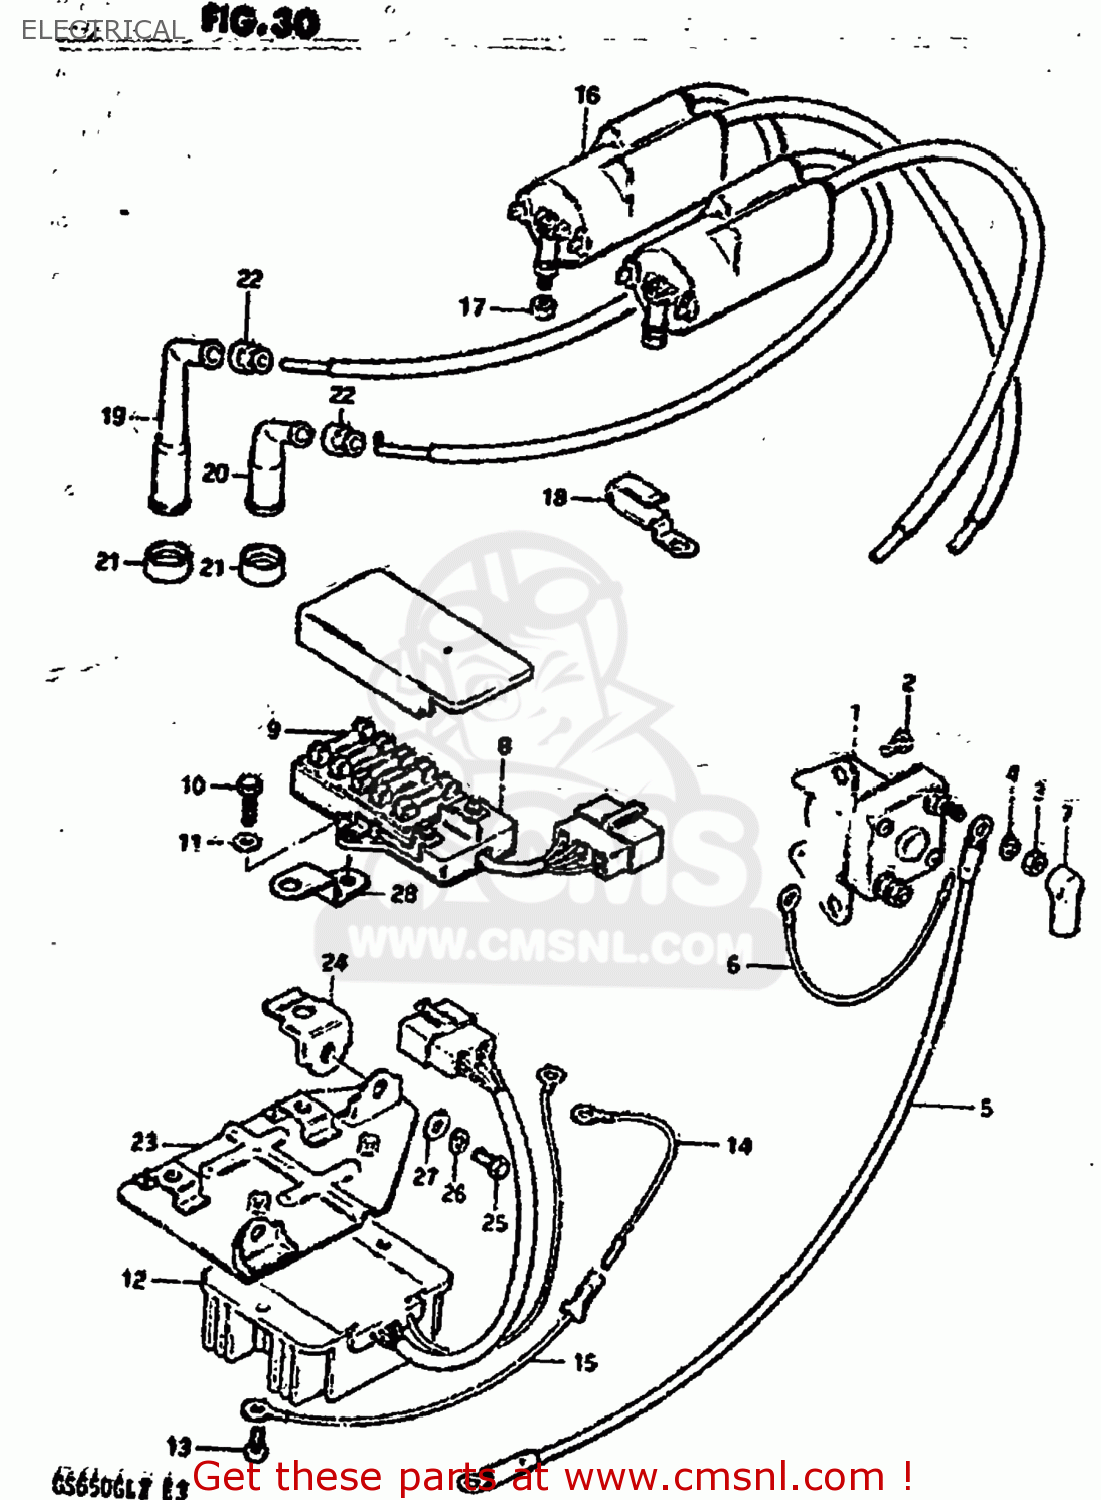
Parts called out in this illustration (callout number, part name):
1	RELAY ASSY,STARTING MOTOR
2	SCREW
3	NUT 6MM
4	LOCK WASHER
5	WIRE,STARTER MOTOR LEAD
6	LEAD WIRE
7	CAP,STARTER RELAY
8	BOX ASSEMBLY,FUSE
9	FUSE(10A)
10	BOLT, UPPER
11	WASHER
12	RECTIFIER ASSEMBLY
13	SCREW 6X12
14	LEAD WIRE
15	WIRE
16	COIL ASSEMBLY,IGNITION
17	NUT
18	CLAMP
19	CAP ASSY,SPARK PLUG
20	CAP,SPARK PLUG
21	SEAL,SPARK PLUG
22	SEAL, SPARK PLUG
23	PLATE,ELECTRIC PARTS H
24	BRACKET, PARTS HOLDER
25	BOLT
26	LOCK WASHER
27	WASHER
28	BRACKET
